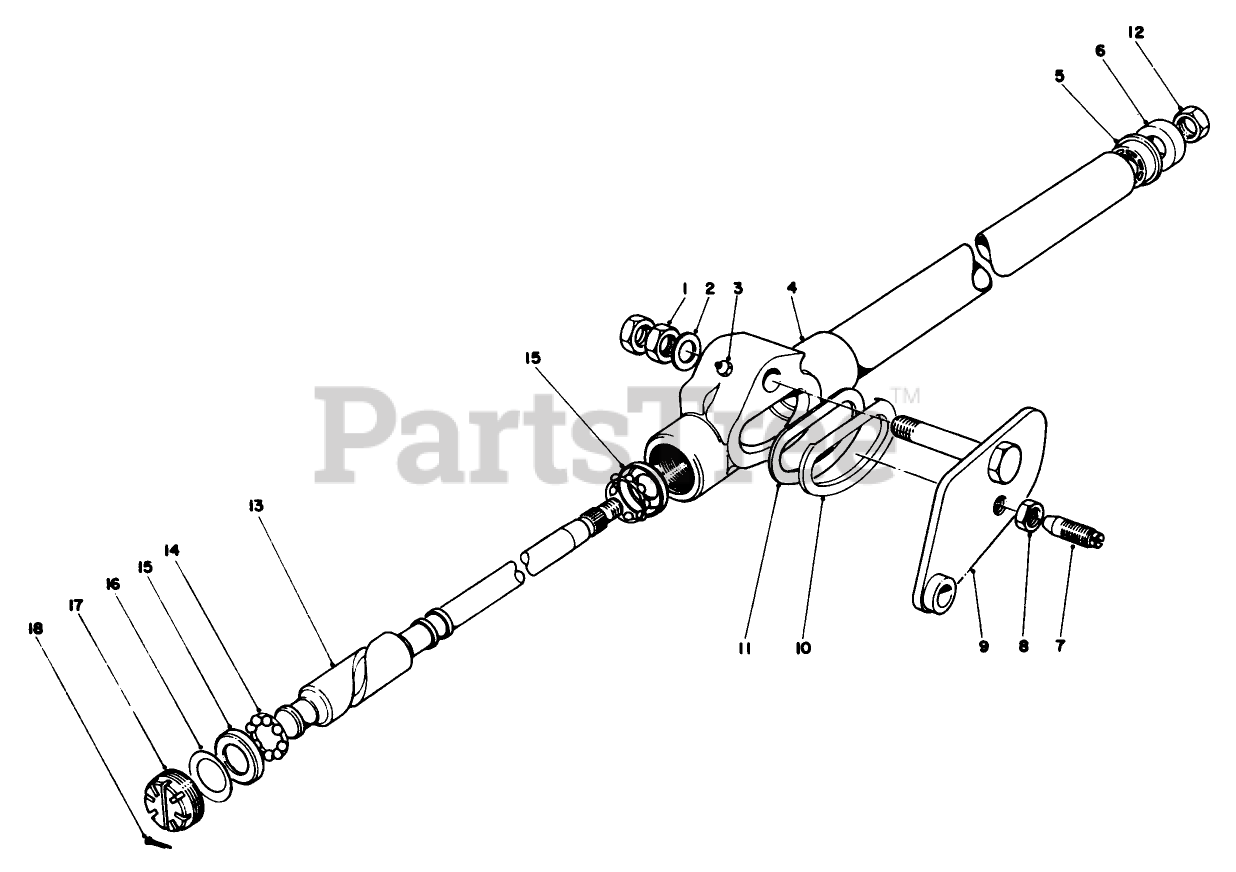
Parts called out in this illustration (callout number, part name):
1	NUT-JAM
2	Washer
3	ZERK FITTING
4	Inner Tunnel
5	BUSH & RETAINER ASM
6	COVER-DUST
7	LEVER STUD
8	NUT-HEX
9	LEVER & BOLT ASM
10	SEAL RETAINING
12	NUT-JAM
13	Cam & Tube Assembly
14	RETAINER & BALL ASM
15	BalI Cup
16	WASHER-BELLEVILLE
17	ADJUSTING PLUG
18	PIN-COTTER
